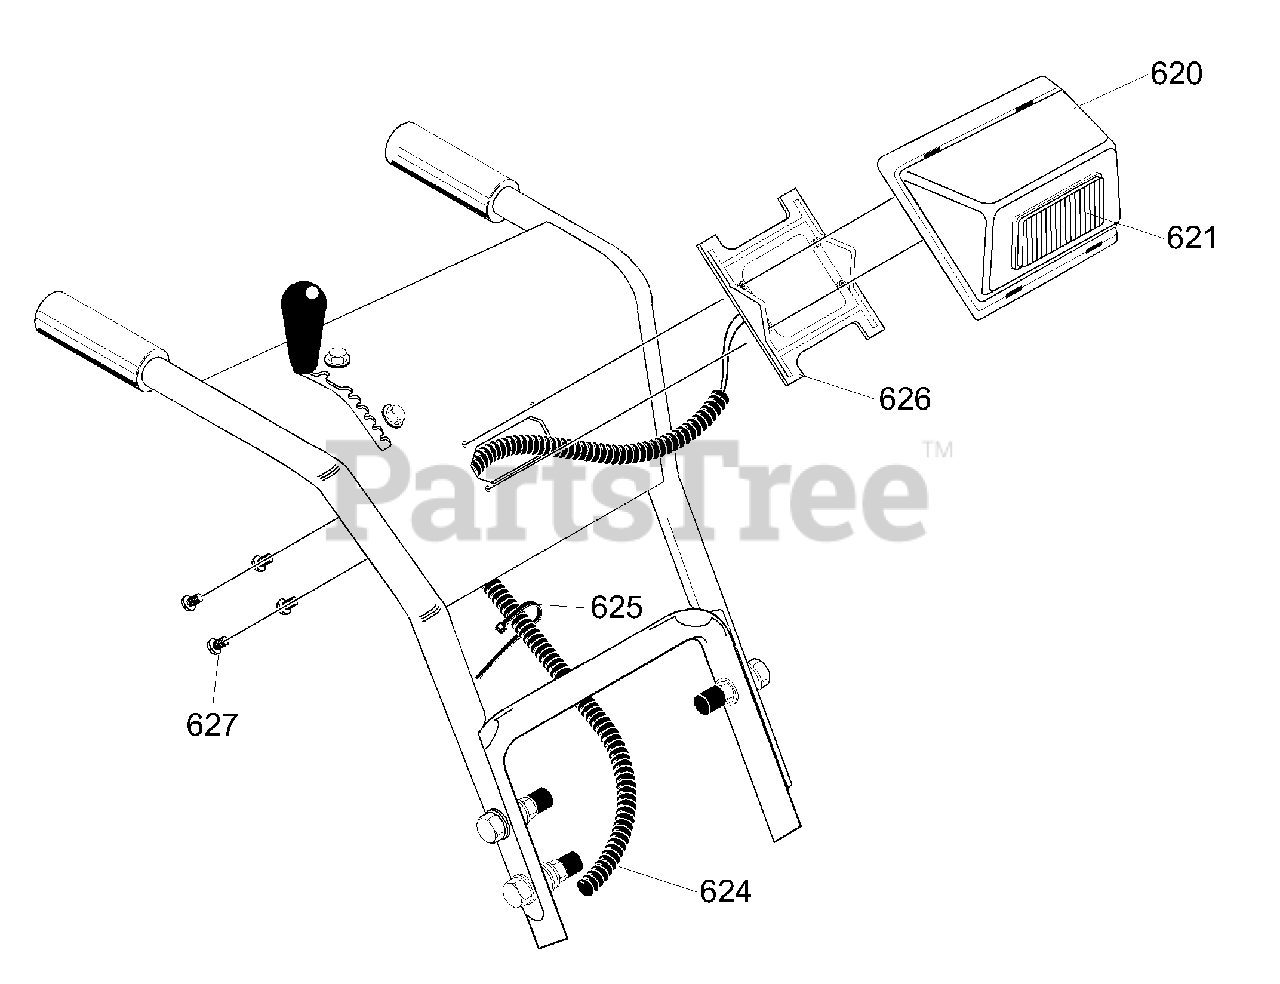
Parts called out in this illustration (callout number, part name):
620	HOUSING, LIGHT B/S
621	HEADLIGHT, ASSY
624	ASSY, HDLIGHT WIRE HARNESS
625	TIE, CABLE
626	BRACKET, LIGHT PANEL
627	SCREW, #8X.75 PANTAPPLAST
